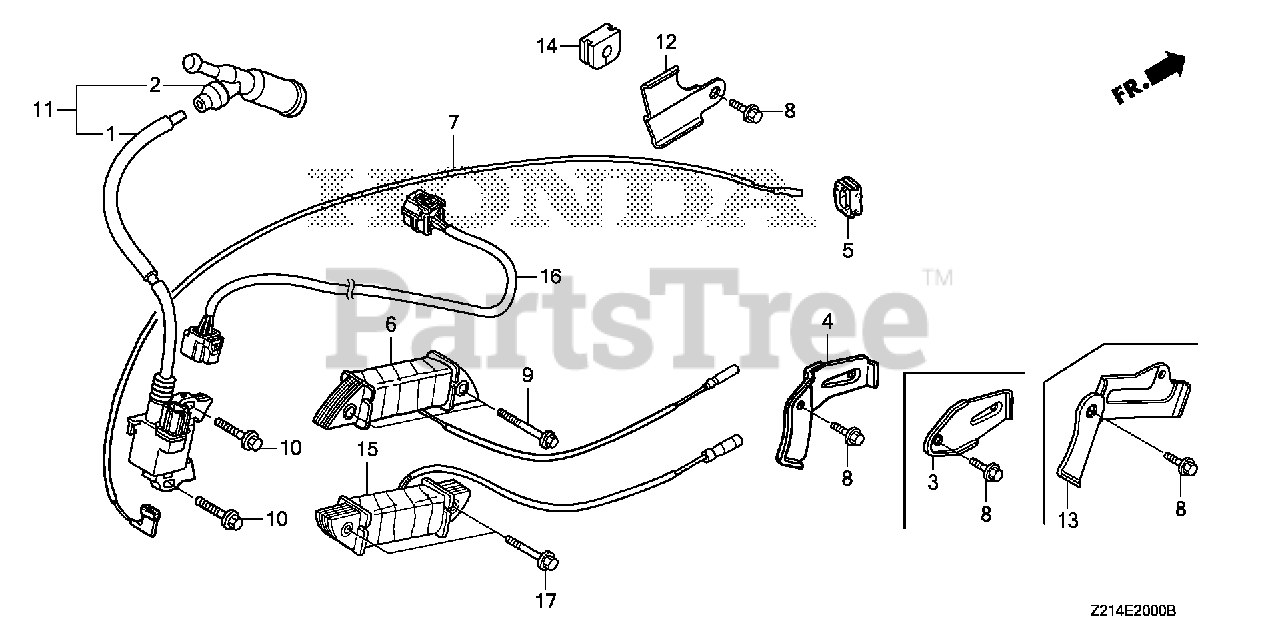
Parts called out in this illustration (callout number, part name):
1	COIL ASSY., IGNITION
2	CAP ASSY., NOISE SUPPRESSOR (NGK Y-EZDB)
4	CLAMP, WIRE
5	GROMMET, WIRE
6	COIL ASSY., CHARGE (1A)
7	WIRE, STOP SWITCH (470MM)
8	BOLT, FLANGE (6X12) (CT200)
9	BOLT, FLANGE (6X35) (CT200)
10	BOLT, FLANGE (6X28) (CT200)
